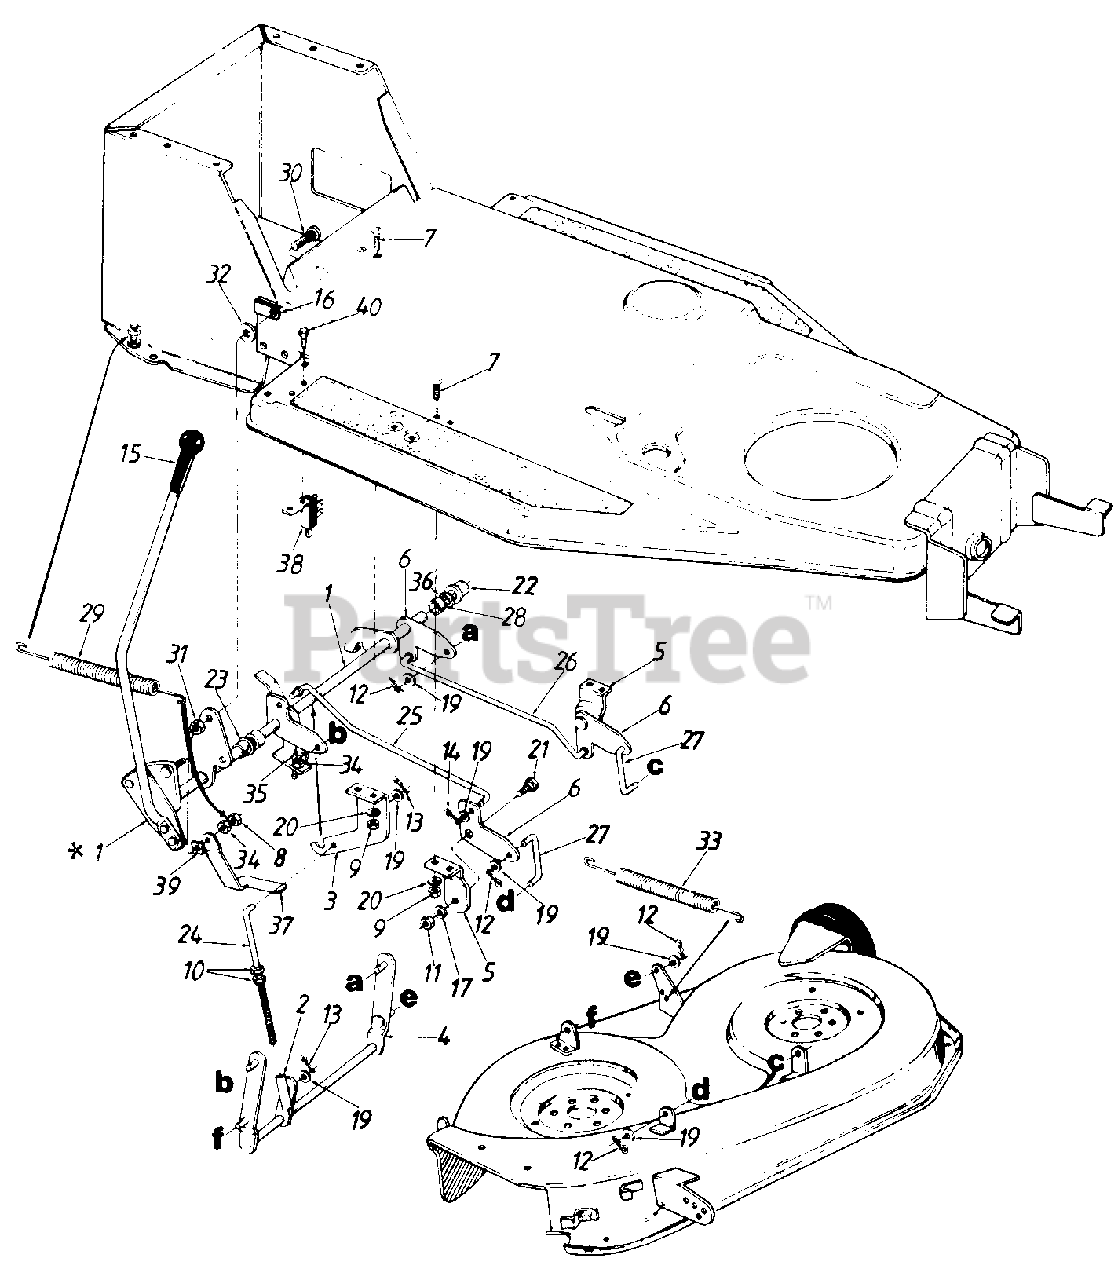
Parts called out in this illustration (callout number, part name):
1	Lift Shaft Ass'y.
2	Pivot Sleeve Ass'y.
3	Deck Lock Out Brkt.
4	Stabilizer Ass'y.
5	Deck Lift Hanger
6	Deck Lift Float Brkt.
7	Carr. Bolt 1/4-20 x .62" Lg.
8	Hex L-Nut 5/16-18 Thd.
9	Hex Nut 1/4-20 Thd.
10	Hex L-Nut 3/8-24 Thd.
11	Hex Nut 3/8-16 Thd.
12	Intern. Cot-Pin 5/16" Dia.
13	Cot-Pin 118" Dia.
14	Cot-Pin 3132" Dia.
16	Clamp
17	L-Wash. 3/8 I.D.
19	Fl-Wash. .406" I.D. x .75" O.D.
20	L-Wash. 1/4" I.D.
21	Shld. Bolt .625 Dia. x .170" Lg.
22	Hex Flange Brg.
23	Nyliner Flanged Brg.
24	J-Bolt 3/8-16 x 5.25" Lg.
25	Connecting Rod-R.H.
26	Connecting Rod-L.H.
27	Lift Link
28	Spacer
29	Spring 8.65" Lg.
30	Ribbed Neck Bolt 3/8-24 x .80" Lg.
31	Hex Nut 3/8-24 Thd.*
32	Fl-Wash. 3/8" I.D.
33	Deck Spring 10.33" Lg.
34	Hex Nut 5/16-18 Thd.*
35	Hex Wash. Hd. Tap Scr. 5/16-18 x 1.0" Lg.
36	Spr. Wash. .625" I.D.
39	L-Wash. 5/16" I.D.
40	Hex AB-Tap Scr. #10 x .5" Lg.
